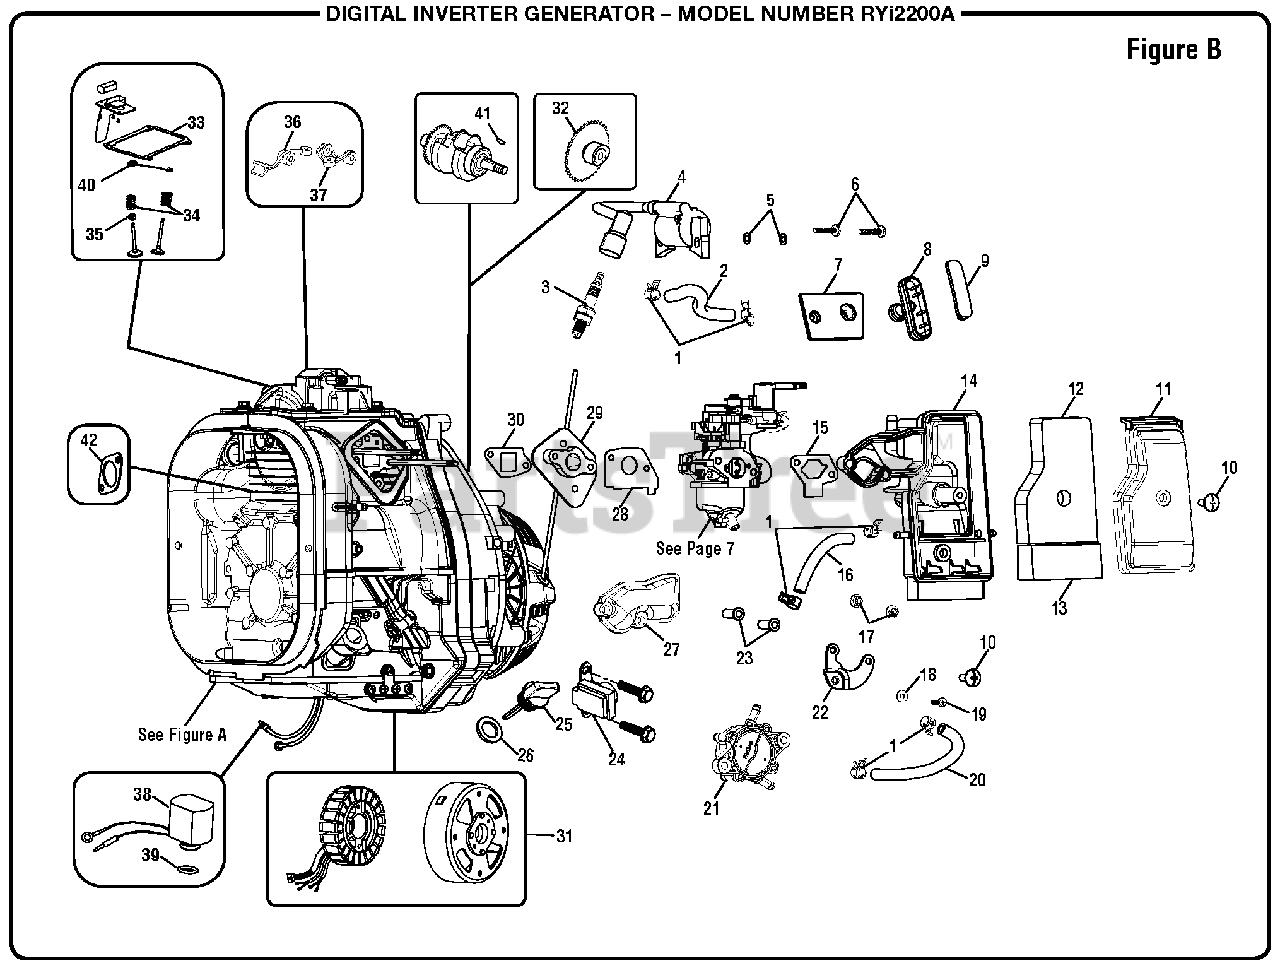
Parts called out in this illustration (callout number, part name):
1	Fuel Hose Clamp (9.5 mm)
2	Vapor Hose/ Air-Box To Engine
4	Ignition Coil
5	Washer (M5)
6	Screw (M4.8 x 19 mm)
7	Start Rope Cover
8	Recoil Handle
9	Handle Cover
10	Screw (M8 x 16 mm, Truss Hd.)
11	Air Cleaner Baffle
12	Air Cleaner Filter (Upper)
13	Air Cleaner Filter (Lower)
14	Air Cleaner Body
15	Intake Pipe Gasket
16	Fuel Hose (Fuel Pump To Fuel Valve, 95 mm)
17	Flange Nut (M5)
18	Washer (ID4.2 x OD10 x 1t)
19	Screw (M4.2 x 12 mm, Pan Hd.)
20	Fuel Hose (Engine To Fuel Pump, 140 mm)
21	Fuel Pump
22	Fuel Pump Bracket
23	Air Cleaner Body Nesting
24	Pick-up Coil
25	Engine Oil Dipstick
26	Oil Dipstick Seal
27	Intake Pipe Top Hood
28	Carburetor Gasket
29	Intake Seat
30	Insulating Board Gasket
31	Alternator Assembly
32	Engine Cam
33	Head Gasket
34	Valve spring
36	Intake Rocker Assembly
37	Exhaust Rocker Assembly
38	Oil Sensor
39	Oil Sensor Seal
40	Valve Retainer
41	Engine Shaft Key
42	Exhaust Pipe Gasket
